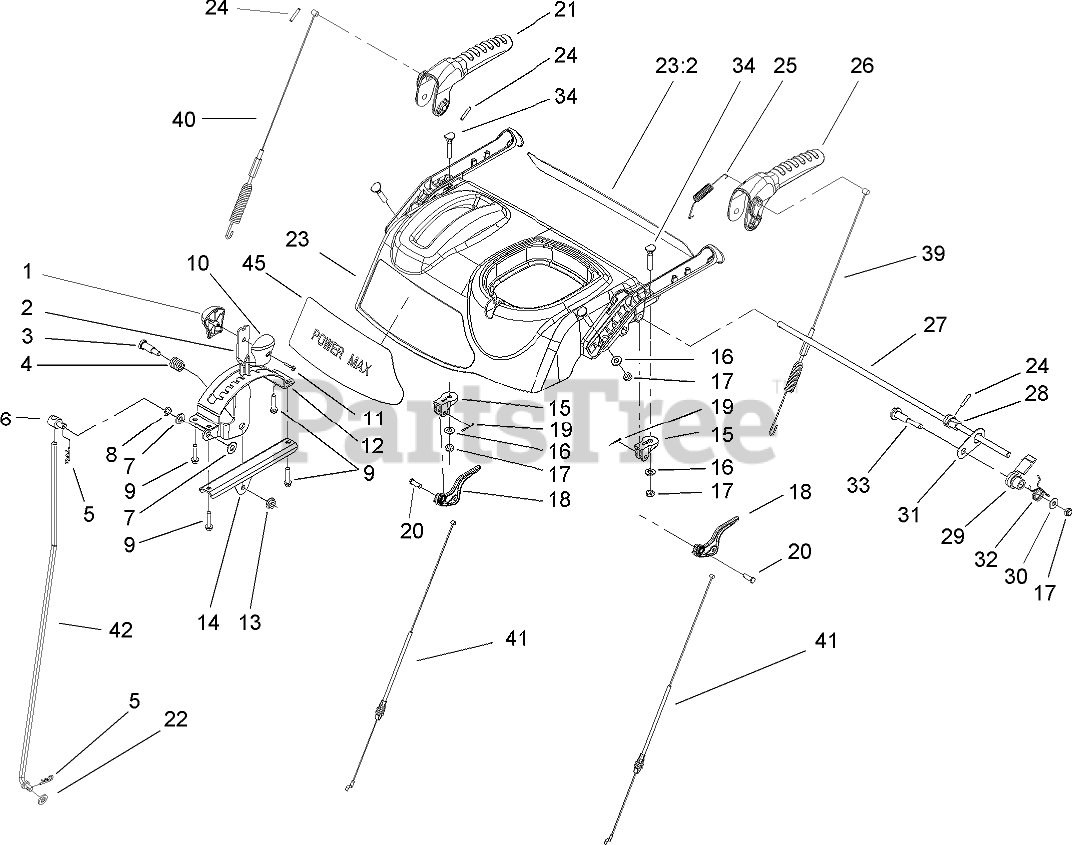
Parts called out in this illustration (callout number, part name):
1	KNOB-SHIFT, RH
2	SELECTOR-SPEED
3	SCREW-SHOULDER
4	SPRING-COMPRESSION
5	PIN-COTTER
6	TRUNNION
7	WASHER-FLAT
8	WASHER-SPRING
9	SCREW-PLASTITE
10	KNOB-SHIFT, LH
11	SCREW-PPH
12	GUIDE-SELECTOR, SPEED
13	NUT-HF
14	MOUNT-SELECTOR, SPEED
15	MOUNT-CLUTCH, LEVER
16	WASHER-FLAT
17	NUT-LOCK, NI
18	LEVER-CLUTCH
19	PIN-COTTER
20	PIN-CLEVIS
21	LEVER-AUGER
22	WASHER-FLAT
23	CONTROL PANEL ASM
24	PIN-SPRING
25	SPRING-TENSION
26	LEVER-TRACTION
27	ROD-LOCKOUT
28	CAM-LOCKOUT
29	LATCH-LOCKOUT
30	WASHER-FLAT
31	LINK-LOCKOUT
32	SPRING-TORSION
33	SCREW-SHOULDER
34	SCREW-HANDLE
39	CABLE-TRACTION
40	CABLE-AUGER
41	CABLE-CLUTCH
42	ROD-SHIFT
45	DECAL-PANEL, CONTROL
